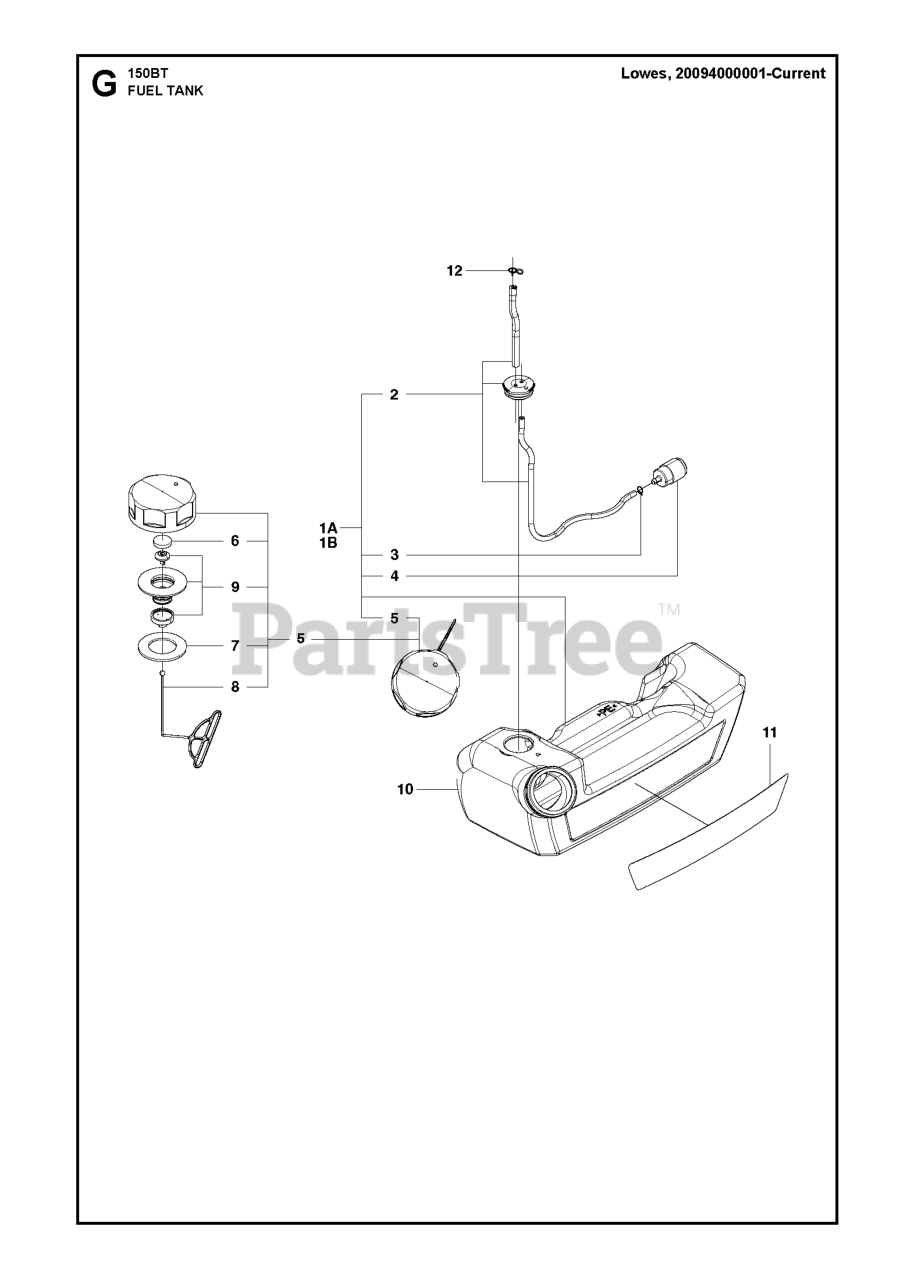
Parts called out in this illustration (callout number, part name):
1	FUEL TANK ASSY
2	RP_PIPE COMPLETE
4	FILTER ASSY
5	ASSY FUEL CAP
